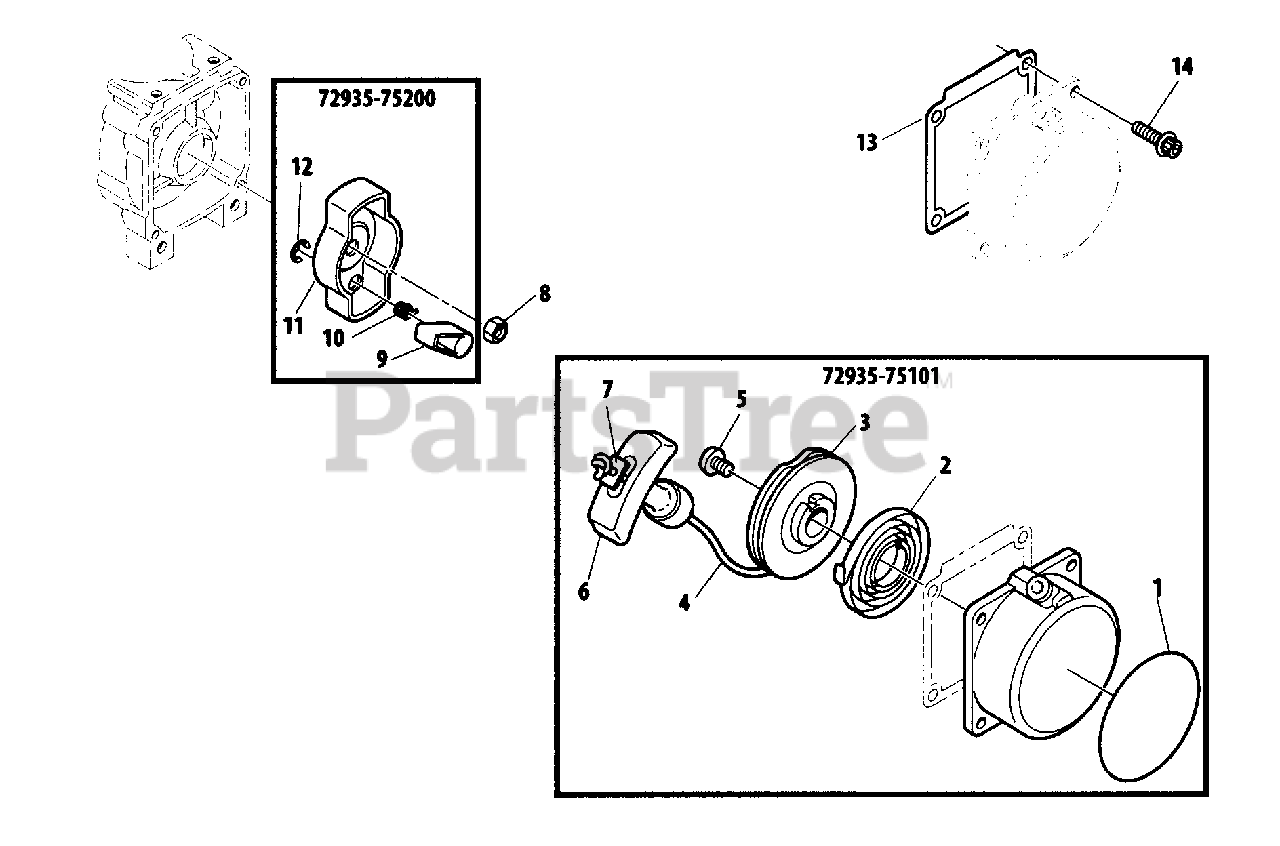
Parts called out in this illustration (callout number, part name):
1	LABEL, TRADE
2	SPRING, RECOIL
3	REEL, ROPE
4	ROPE, STARTER
5	SCREW 5
6	GRIP, STARTER
7	RETAINER, ROPE
8	NUT 8
9	PAWL, STARTER
10	SPRING, RETURN
11	PULLEY ASSY, STARTER
12	E-RING 4
13	GASKET, RECOIL STARTER
14	BOLT, ADHESIVE M4×16
72935-75101	STARTER ASSY, RECOIL
72935-75200	PULLEY ASSY, STARTER
